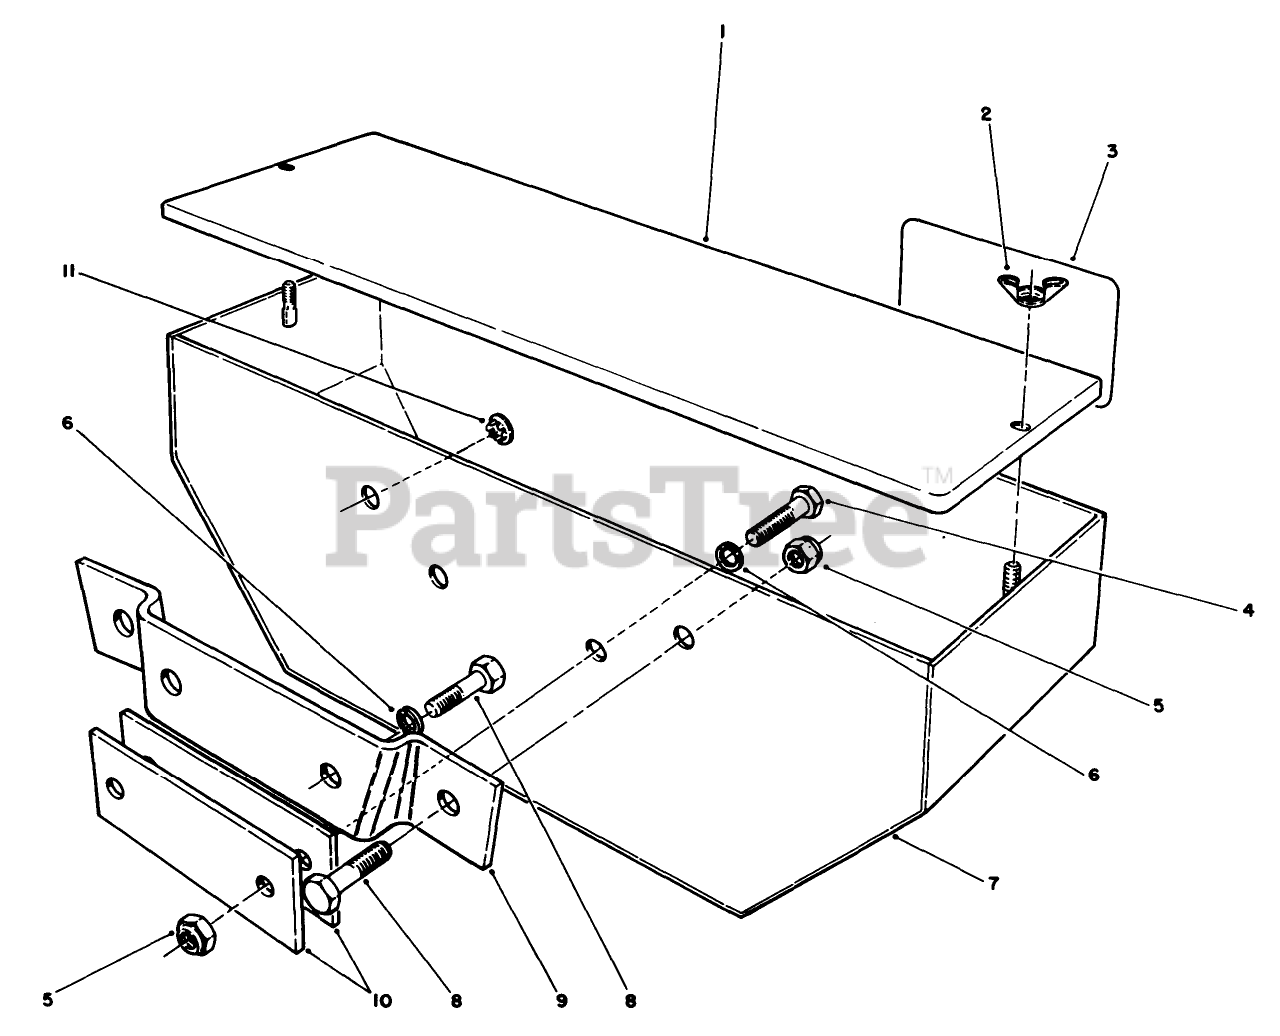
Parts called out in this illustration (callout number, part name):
1	WT BOX COVER *R
2	NUT-WING
4	SCREW-HH
5	NUT-LOCK, NI
6	SCREW-HH
8	SCREW-HH
9	MOUNT BRKT *R
